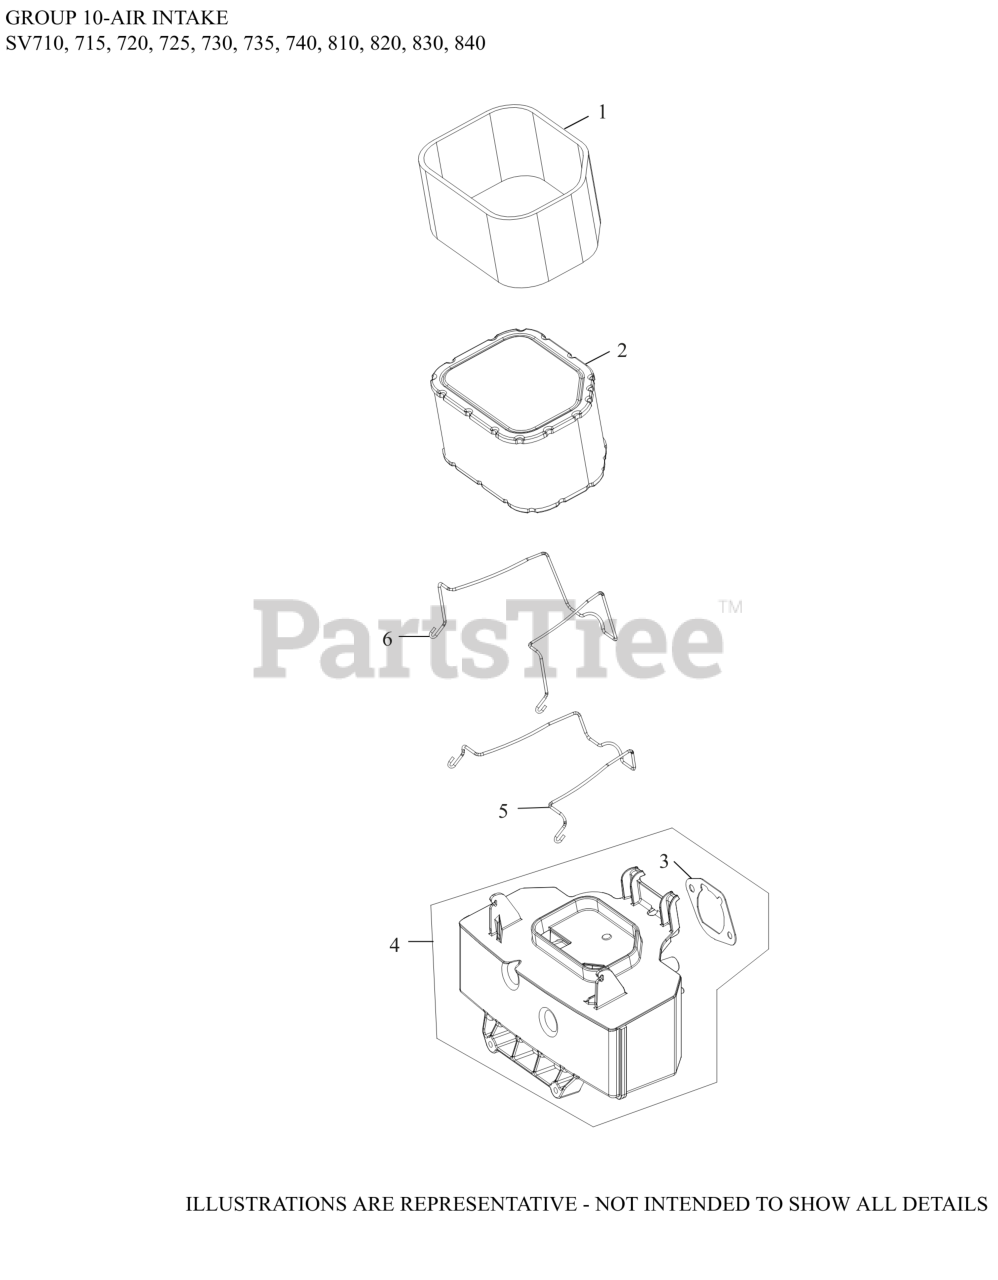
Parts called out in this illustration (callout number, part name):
2	ELEMENT, AIR FILTER
3	GASKET, AIR CLEANER BASE
4	AIR CLEANER BASE-DISCONTINUED
5	LATCH, AIR CLEANER ELEMENT-DISC.
